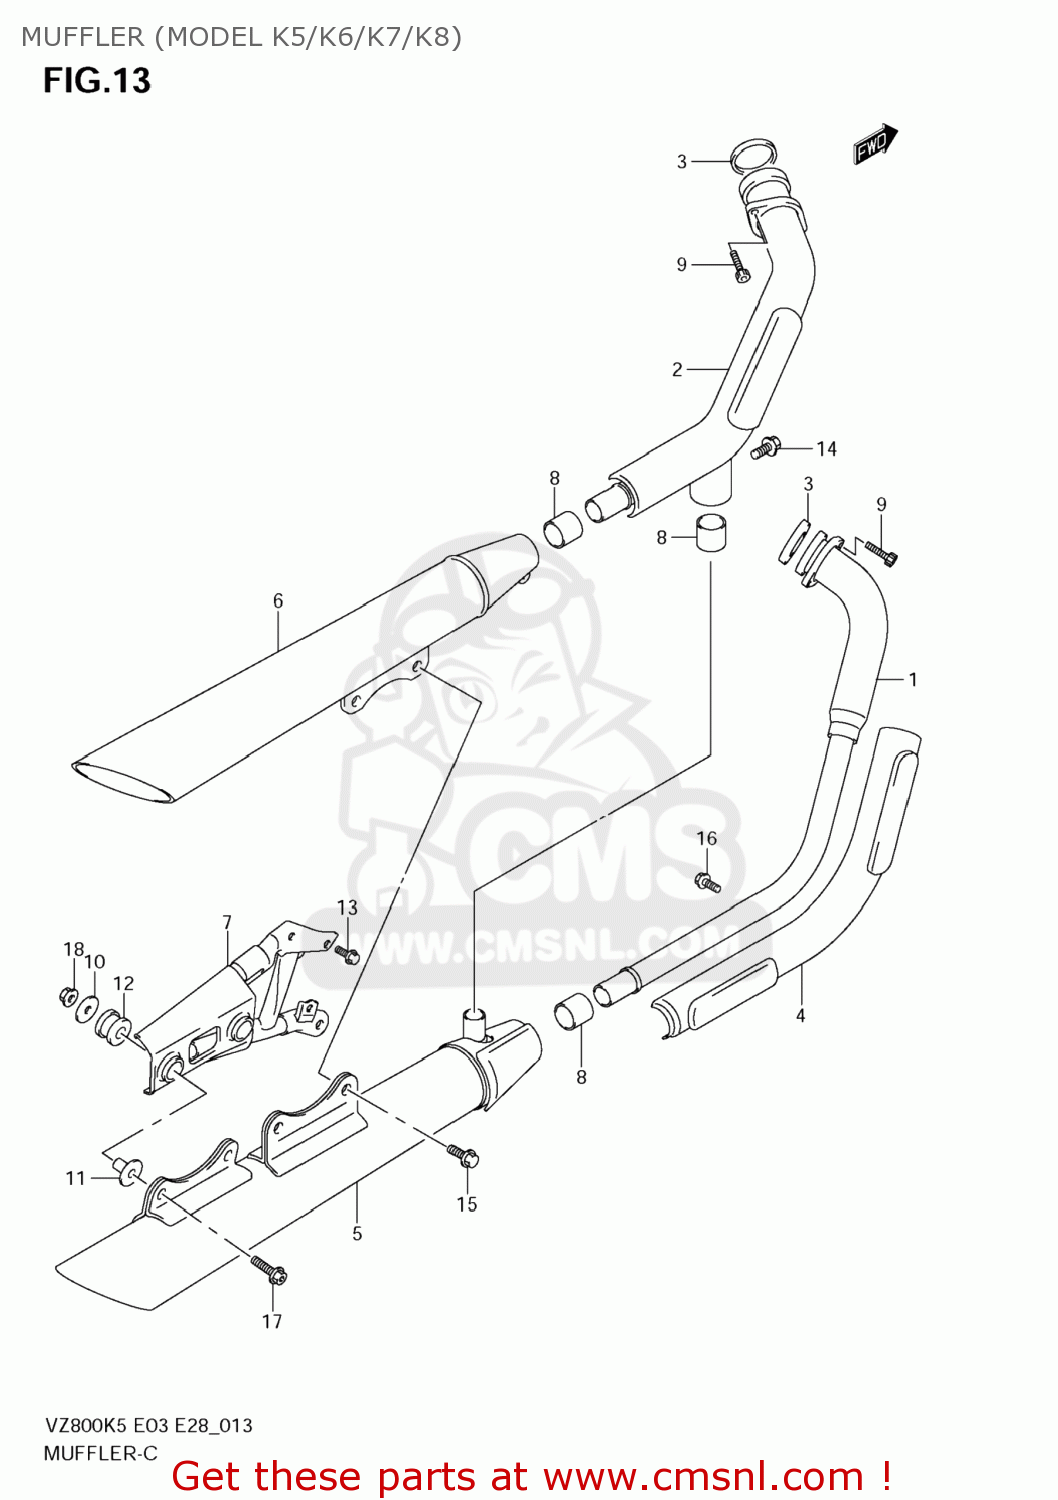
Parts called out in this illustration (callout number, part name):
1	PIPE,EXHAUST FR
2	PIPE,EXHAUST RR
3	GASKET,EXHAUST PIPE (NAS)
4	COVER,EXHAUST FRONT
5	BODY,MUFFLER
6	BODY,MUFFLER
7	BRACKET,MUFFLER SUPPORT
8	CONNECTOR,MUFFLER
9	BOLT(8X25)
10	WASHER (8.5X33X1.6)
11	SPACER(8.6X12X27.1)
12	CUSHION
13	BOLT
14	BOLT
15	BOLT
16	BOLT
17	BOLT(8X16)
18	NUT
